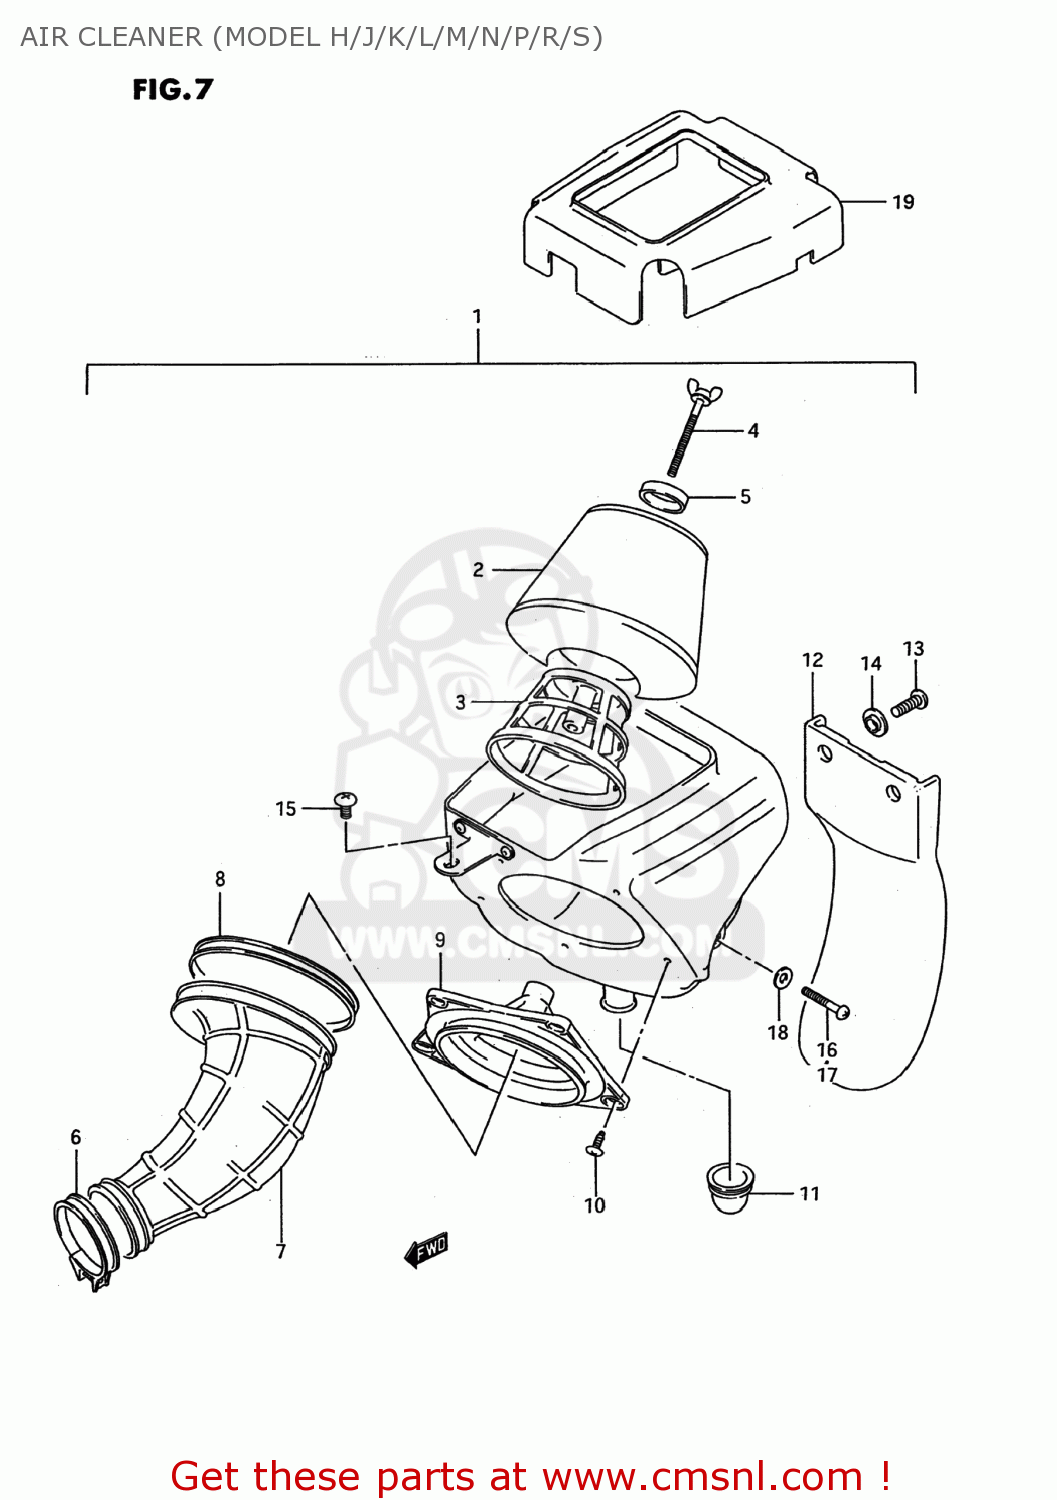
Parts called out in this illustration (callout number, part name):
1	CLEANER ASSEMBLY,AIR
2	FILTER ASSY
3	HOLDER
4	BOLT,WING
5	WASHER,AIR CLEANER
6	CLAMP
7	TUBE,AIR CLEANER OUTLET
8	CLAMP
9	BASE,FILTER
10	SCREW
11	HOSE,AIR CLEANER DRAIN
12	GUARD,MUD
13	SCREW
14	COLLAR
15	SCREW 6X12
16	SCREW
17	BOLT
18	WASHER
19	GUARD,MUD
